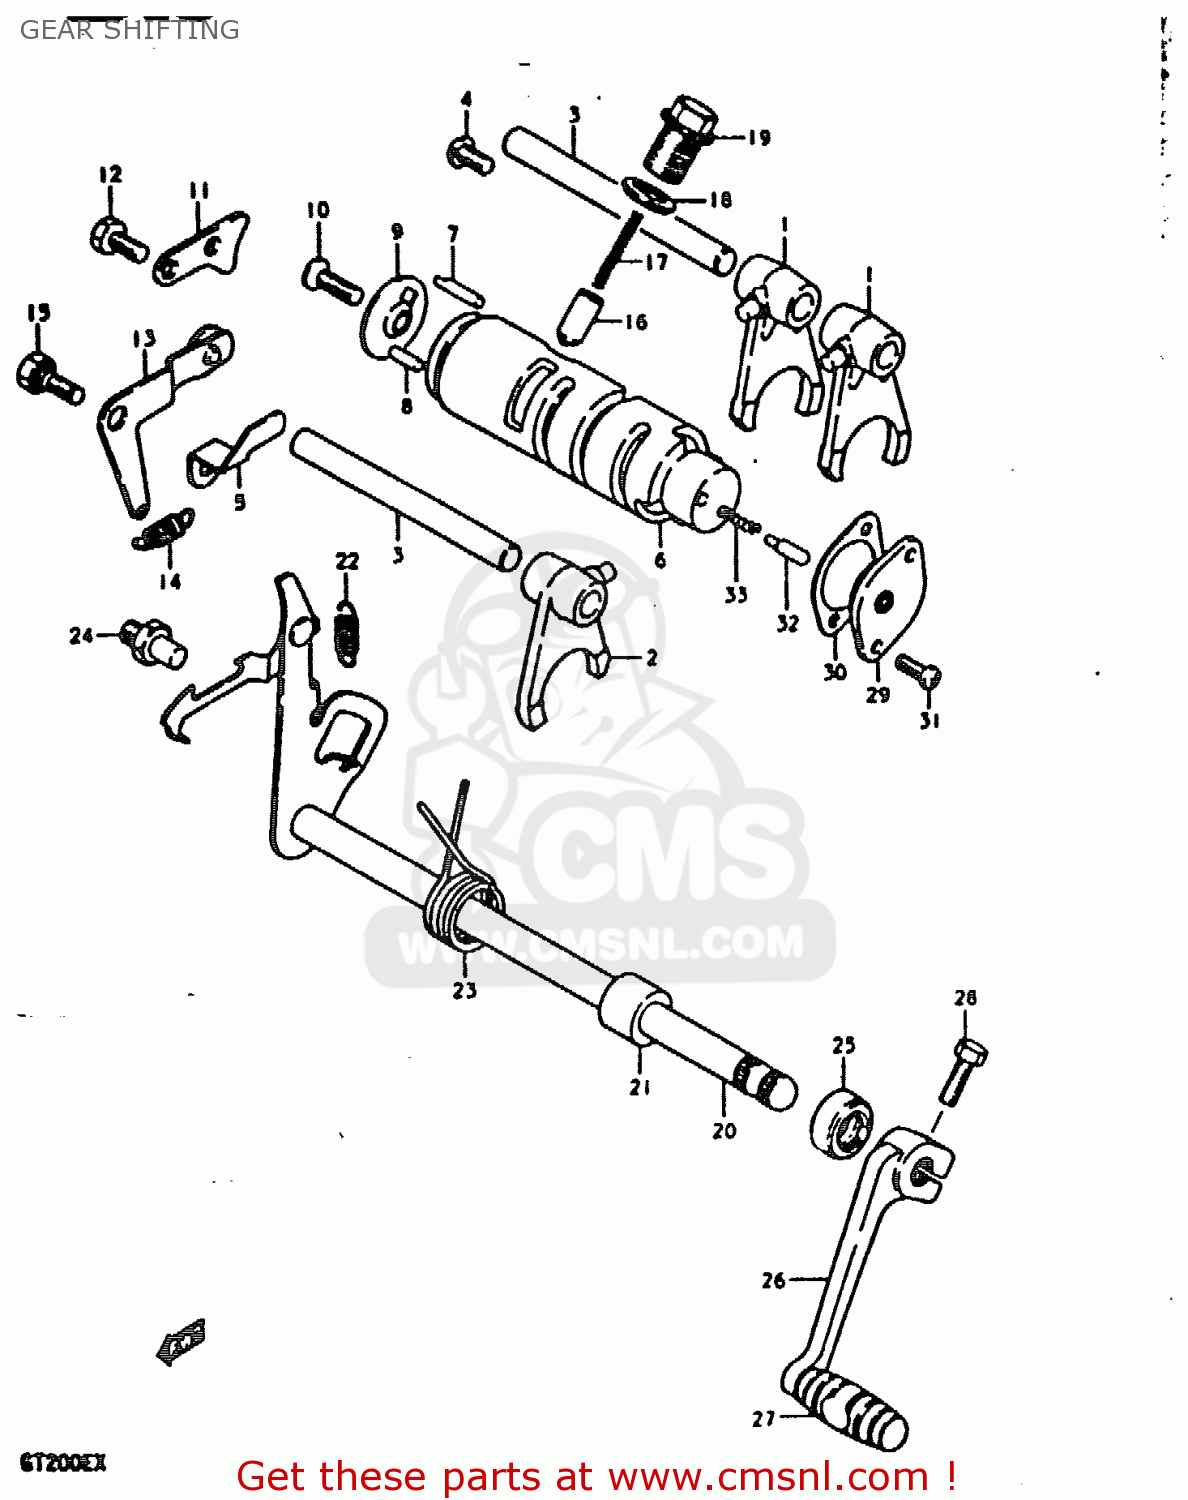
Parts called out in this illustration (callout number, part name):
1	FORK, GEAR SHIFTING NO.1
2	FORK, GEAR SHIFTING NO.2
3	SHAFT,GEAR SHIFT FORK
4	SCREW
5	STOPPER, FORK SHAFT NO.2
6	CAM, GEAR SHIFTING
7	PIN
8	ROLLER(4X13.8)
9	RETAINER, DRIVE PIN
10	SCREW
11	GUIDE,GEAR SHIFT CAM
12	BOLT
13	STOPPER, CAM NO.1
14	SPRING
15	BOLT(6X16.1)
16	STOPPER,GEAR SHIFTING
17	SPRING
18	GASKET(14X19.2X2) (NAS)
19	BOLT,GEAR SHAFT CAM STOPPER
20	SHAFT,GEAR SHIFT
21	SPACER(12X20X15.3)
22	SPRING
23	SPRING
24	STOPPER,GEAR SHIFT CAM
25	OIL SEAL
26	LEVER ASSY, GEAR SHIFTING
27	RUBBER,GEAR SHIFT PEDAL
28	BOLT
29	BODY, GEAR SHIFTING SWITCH
30	GASKET (MCA)
31	SCREW
32	PIN(5X15.5)
33	SPRING
